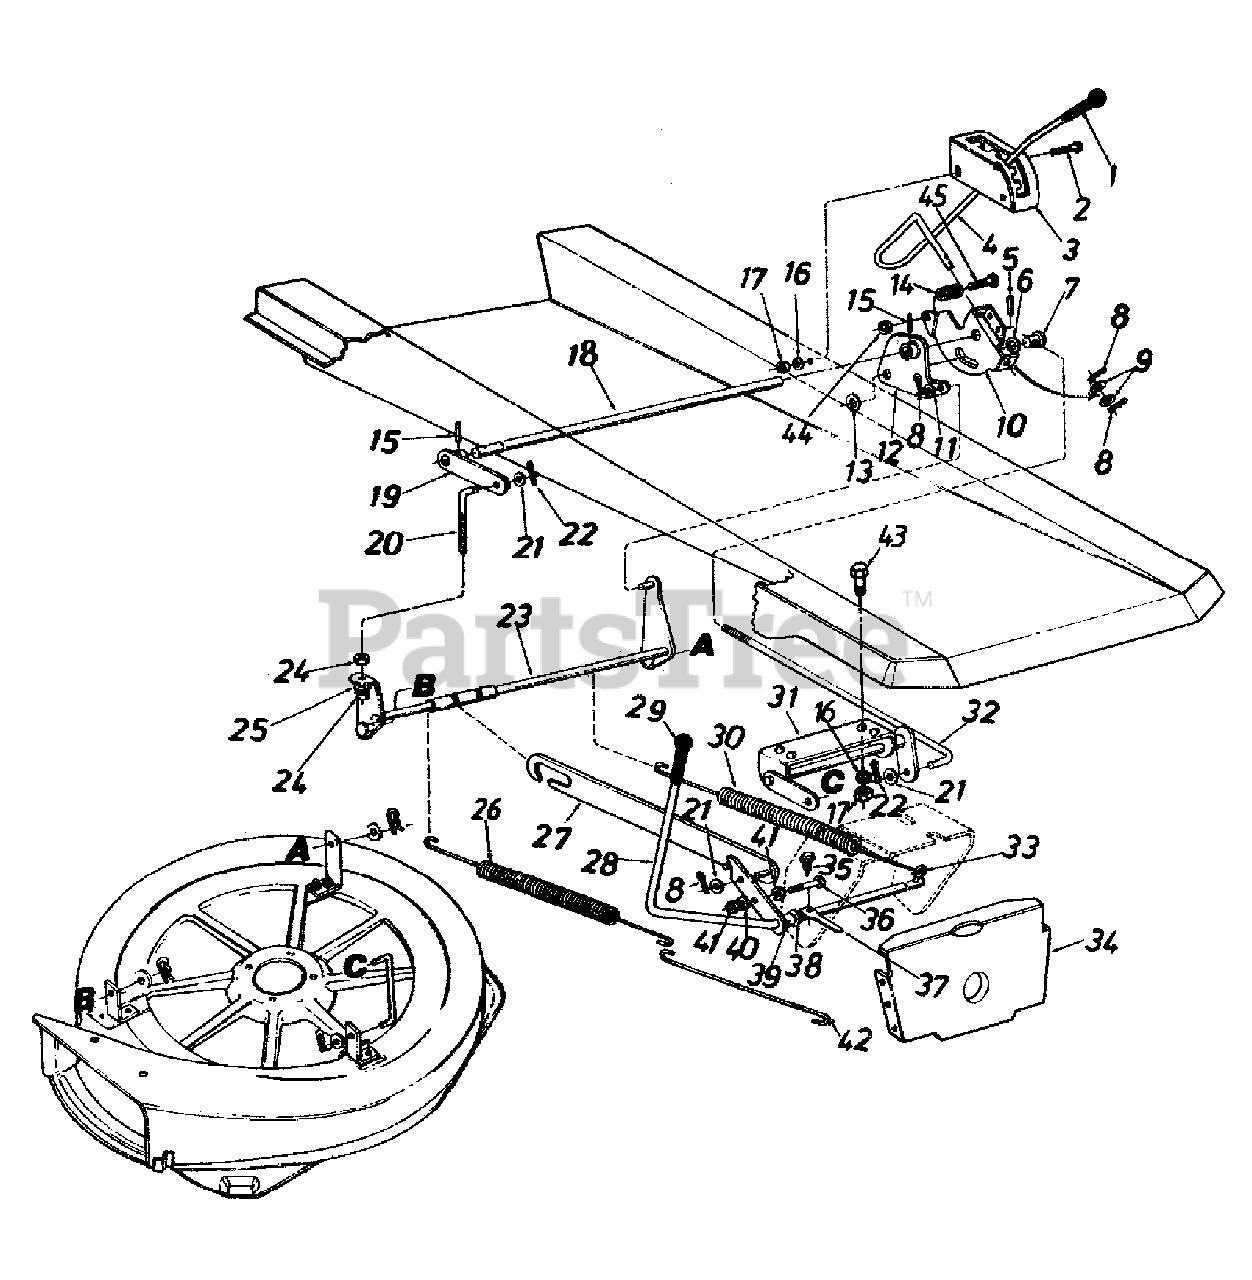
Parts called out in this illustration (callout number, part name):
2	Truss Mach. Scr. 5/16-18 x .75" Lg.
5	Spring Pin Spir. 3/16" Dia. x 1.50" Lg.
6	Fl-Wash. .385" I.D. x .87" O.D.
7	Adj. Ferrule Deck Lift Handle
8	Cotter Pin 1/8" Dia. x 1.0"
9	Fl-Wash. .531" I.D. x .930" O.D.
12	Deck Lift Brkt. Ass'y.-L.H.
13	Fl-Wash. .635" I.D. x 1.04" O.D.
14	Compression Spring .5" Dia. x .9" Lg.
15	Spring Pin Spir. 1/4" Dia. x 1.50" Lg.
16	L-Wash. 5/16" I.D.
17	Hex Nut 5/16-18 Thd.
18	Rear Hgt. Adj. Shaft
19	Deck Lift Brkt. Ass'y.-R.H.
20	Deck Adj. Scr. 3/8-16 Thd.
21	Fl-Wash. .385" I.D. x .87" O.D.
22	Intern. Cotter Pin 1/2" Dia.
23	Deck Link Ass'y.-Rear
24	Hex Nut 3/8-16 Thd.
25	L-Wash. 3/8" I.D.
26	Extension Spring 13.25" Lg.
30	Extension Spring 13.25" Lg.
31	Deck Lift Ass'y.-Front
32	Deck Lift Connecting Rod
33	Clevis Pin Special .250" Dia.
36	Hex Bolt 5/16-18 x 1.50" Lg. (Grade 5)
37	Switch Actuator
38	Fl-Wash. .531" I.D. x .930" O.D.
39	Spacer .511" I.D. x .70" O.D. x .38" Lg.
40	L-Wash. 5/16" I.D.
41	Hex Nut 5/16-18 Thd.
42	Spring Hook
43	Hex Bolt 5/16-18 x .75" Lg.
44	Hex Cent. L-Nut 1/4-20 Thd.
45	Hex Bolt 1/4-20 x 1.25" Lg.
